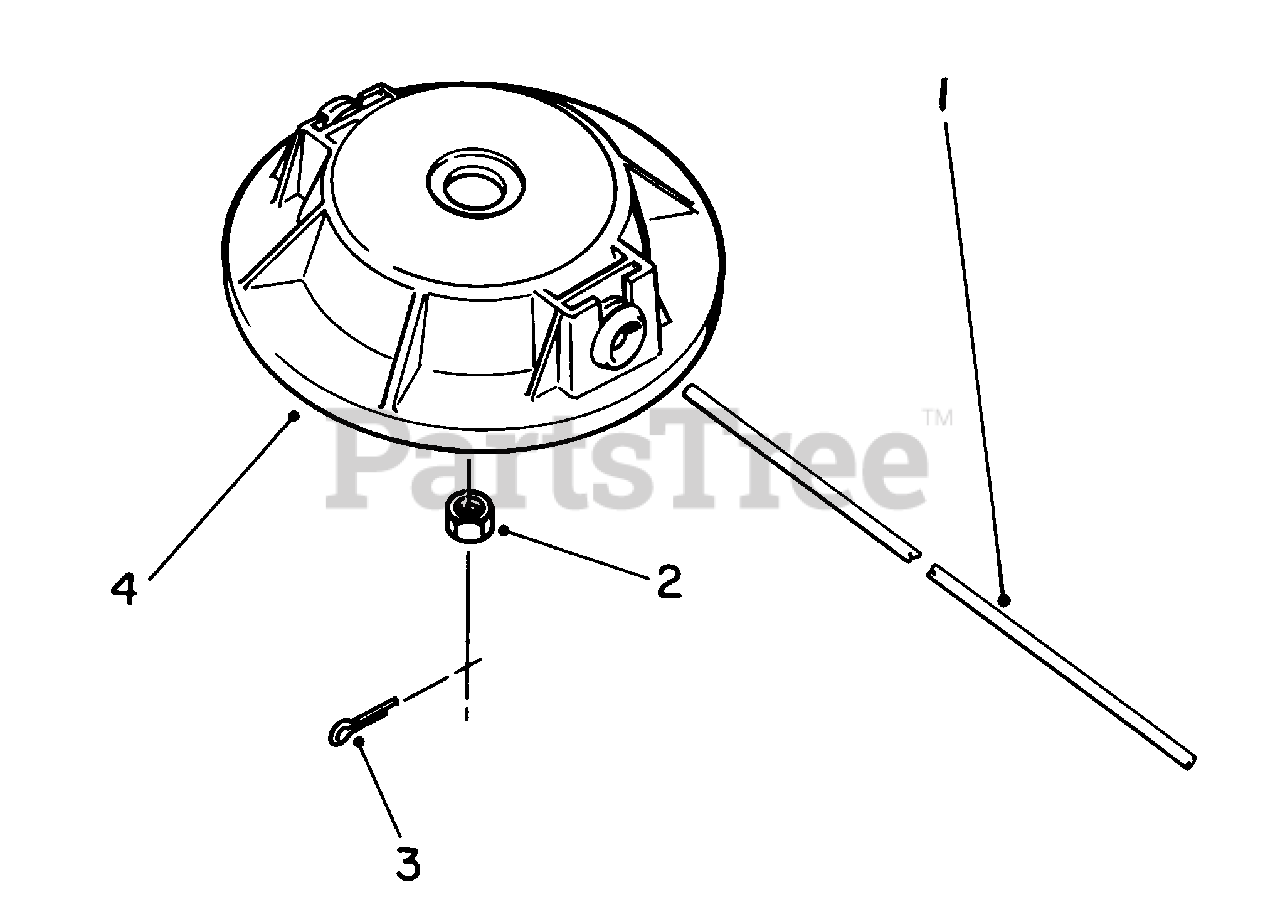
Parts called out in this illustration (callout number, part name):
1	Line-Cutting
2	Nut L.H.
3	Pin-Cotter
4	Cutter Head Assembly
